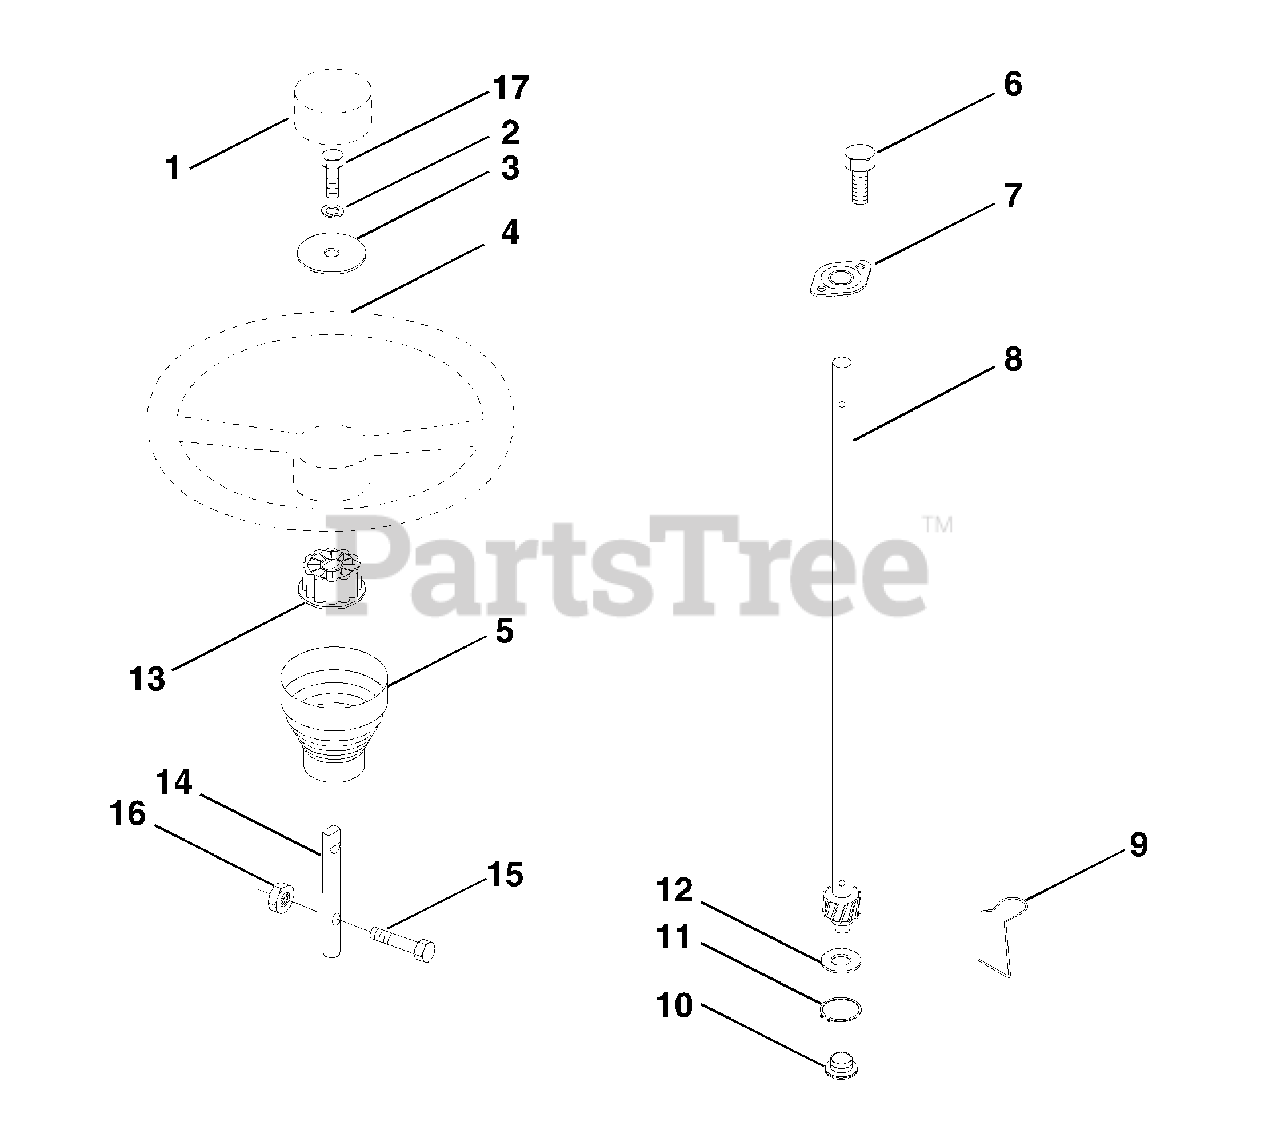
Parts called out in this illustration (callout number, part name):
1	Insert, Wheel, Steering
2	Washer, Lock Hvy Hlcl
3	Washer 12/32 x 2-3/8 x 8 Ga.
4	Wheel, Steering
5	Sleeve, Steering
7	Bushing, Steering
8	Shaft, Steering
9	Clip, Steering
10	Bushing, Lower, Steering
11	Ring, Retaining
12	Washer 21/32 x 1 x 16 Ga.
13	Adaptor, Wheel, Steering
14	Extension Shaft, Steering
15	Bolt, Fin, Hex 5/16-18 Unc
16	Nut, Lock, Hex w/Ins 5/16-18 Unc
17	Bolt, Fin Hex 3/8-16 UNC x 1
